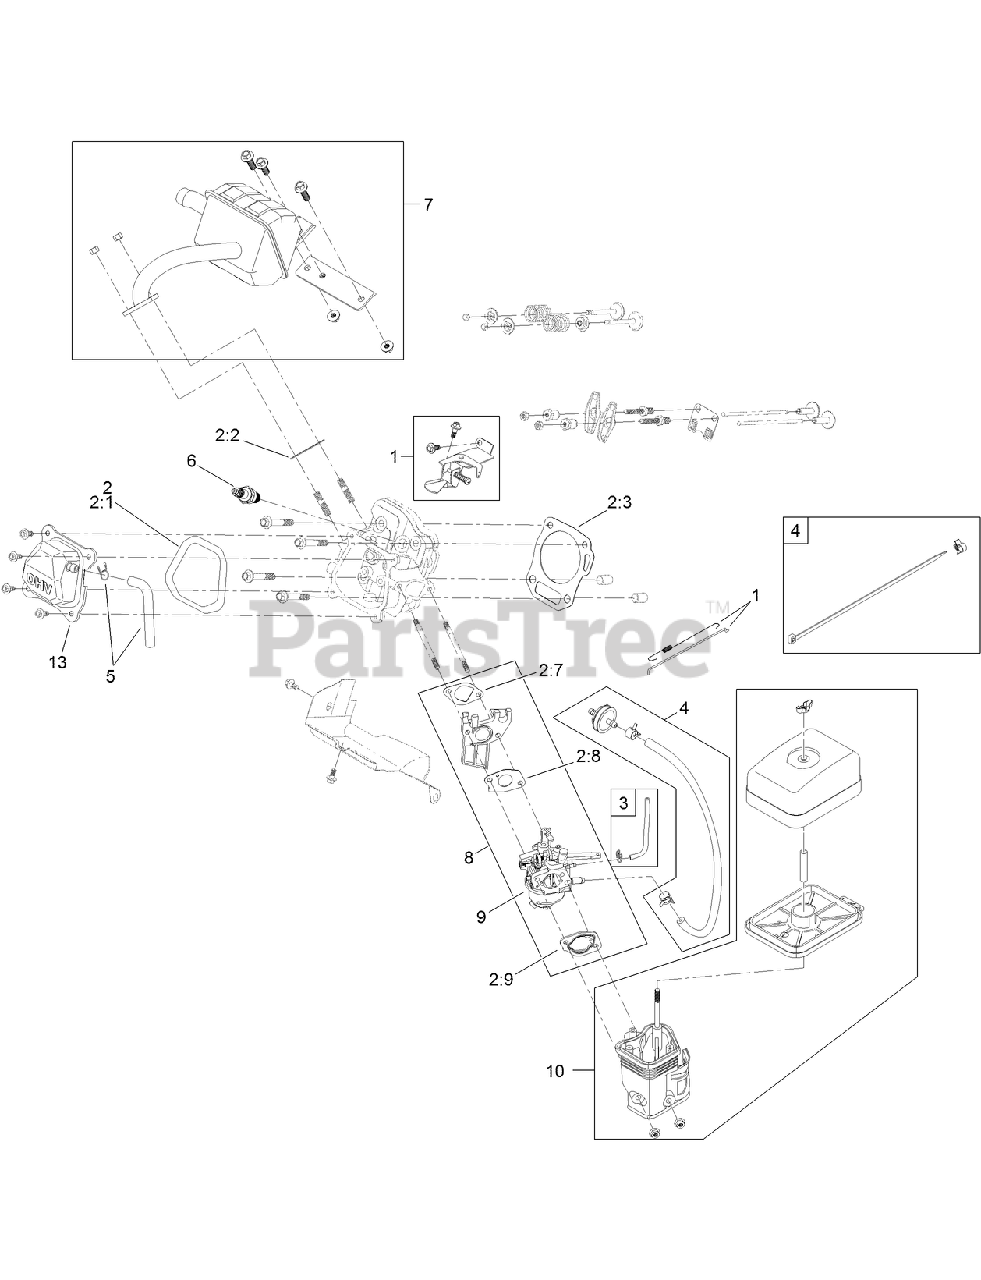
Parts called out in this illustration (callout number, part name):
1	GOVERNOR KIT
2	GASKET AND SEAL KIT
2:1	GASKET-COVER, VALVE
2:2	Gasket-Exhaust
2:3	GASKET-HEAD, CYLINDER
2:4	Loose Parts Package
2:5	Loose Parts Package
2:6	GASKET-COVER, CRANKCASE
2:7	GASKET-CARBURETOR
2:8	GASKET-CARBURETOR
2:9	GASKET-CARBURETOR
4	FUEL LINE KIT
5	BREATHER TUBE KIT
7	MUFFLER KIT
8	CARBURETOR KIT
9	CARB REPAIR KIT WITH GASKETS
10	HEATER BOX KIT
13	VALVE COVER ASM
